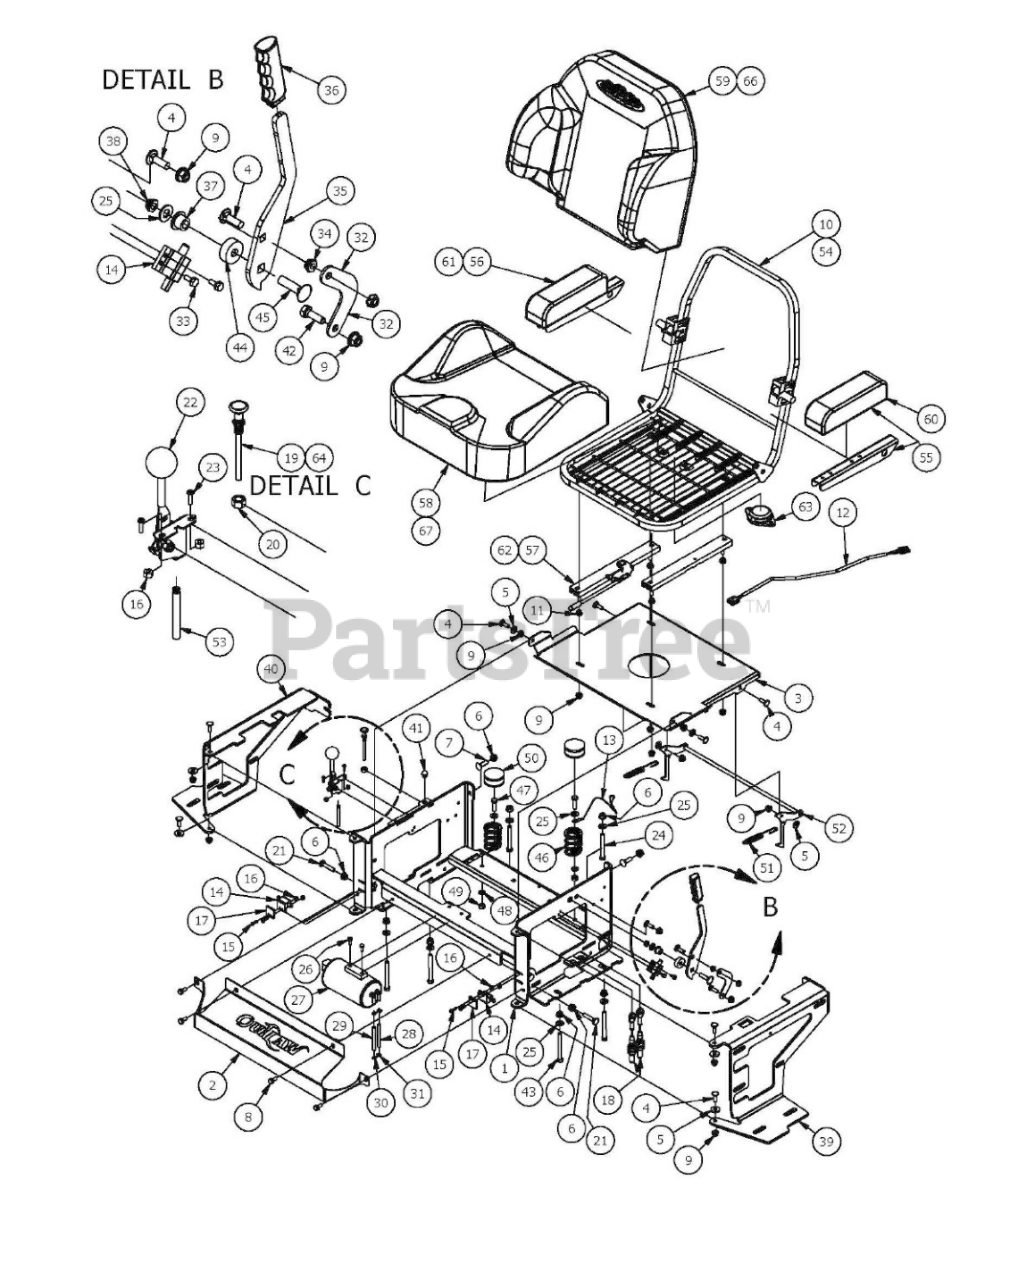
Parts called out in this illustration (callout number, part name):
1	2017 Outlaw Seat Bracket
2	Outlaw Cooler Cover
3	2016 Seat Plate Outlaw
4	5/16-18 x 1 Carriage Bolts Zinc
5	.360 ID Plastic Washer
6	3/8" Nylock Flange Nut
7	3/8" x 1 1/4" Carriage Bolt
8	5/16 x 3/4 washer head type F screw
9	5/16" Nylock Flange Nut Zinc
10	2015 Outlaw Seat (Extreme Outlaw Only)
11	5/16" Flange Nut
12	Seat Switch Adapter
13	Seat Cable
14	Safety Switch
15	10-24 x 1 BS C/S 18-8 SS
16	10-24 Nylon Insert Locknut
17	Switch Block Plastic
18	Long Brake Cable
20	3/8" Fine Threaded Jam Nut
21	3/8 x 1 3/4 Carriage Bolt
22	Universal Throttle
23	10-24 X 5/8 BS Button Head Bolt
24	3/8-16x3 grade 5 hex bolt
25	3/8" Flat Washer
26	M6-1.0 X 16MM Hex Bolt
27	Carbon Canister
28	1/4" Vinyl Tubing
29	3/16 Vinyl Tubing
30	3/16" Vinyl Hose Clamp
31	3/16 Vinyl Clamp
32	Brake Cable Adapter Bracket
33	12-24x 1/2 HWH Bolt
34	5/16-18 Nylock Jam Nut 1/2 Nut
35	Brake Handle Cam Over
36	Rubber Brake Grip-cZT/ZT 2013
37	Bronze Bushing SF-1220-8
38	3/8-16 Hex Flange Top L/N
39	Outlaw 2016 Tank Support (Left)
40	Outlaw 2015 Tank Support (Right)
41	Black Plug- 5/8" Head (EFI Engines Only)
42	5/16" x 1" Bolt
43	3/8-16x3-1/2 grade 5 hex bolt
44	2015 Brake Lever Spacer
45	3/8 x 1 1/2 Carriage Bolt
46	Seat Spring
47	3/8" x 1 1/4" Hex Bolt
48	3/8" Lock Washer
49	3/8" Hex Nut
50	Spring Cap Cover
51	Brake Spring
52	Seat Latch Rod Assembly 2016 Models
53	Outlaw Throttle Cable (Cable Only)
54	2016 Outlaw Seat (Base Outlaw Only)
55	Base Outlaw Seat Arm Left
56	Base Outlaw Seat Arm Right
57	Base Outlaw Seat Rails (Pair)
58	Extreme/XP Outlaw Seat Cushion - Bottom
59	Extreme/XP Outlaw Seat Cushion - Back
60	Extreme/XP Outlaw Seat Arm Pads Only (Pair)
61	Extreme/XP Outlaw Seat Arm Rest (Pair)
62	Extreme/XP Outlaw Seat Rails (Pair)
63	Seat Switch
64	FX850 & FX730 Kawasaki Choke Cable
66	Back Seat Cover (Base Outlaw)
67	Bottom Seat Cover (Base Outlaw)
